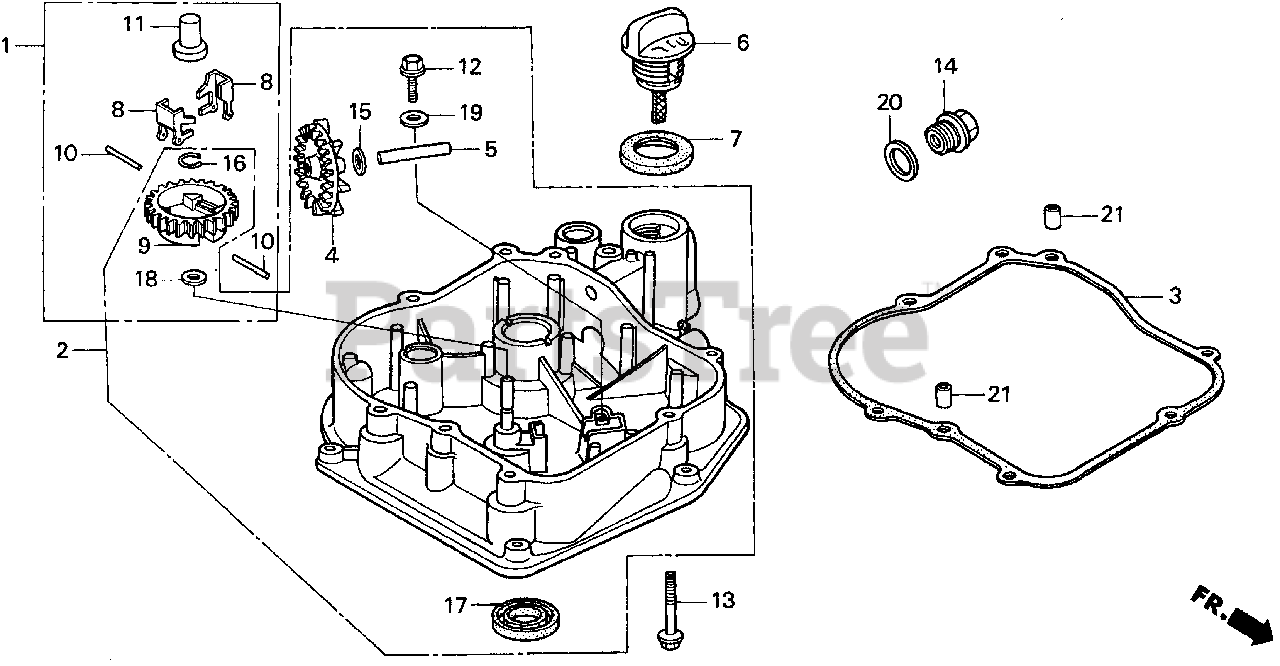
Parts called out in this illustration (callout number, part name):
1	GOVERNOR KIT (STD)
2	PAN ASSY., OIL
3	GASKET, CASE COVER
4	SLINGER, OIL
5	SHAFT, OIL SLINGER
6	CAP, OIL FILLER
7	GASKET, OIL FILLER CAP Use up to Engine SN 1257294.
8	WEIGHT, GOVERNOR
9	HOLDER, GOVERNOR WEIGHT
10	PIN, GOVERNOR WEIGHT
11	SLIDER, GOVERNOR
12	BOLT, FLANGE (5X16)
13	BOLT, FLANGE (6X28) (CT200) Use up to Engine SN 1530314.
14	BOLT, DRAIN PLUG (20MM)
15	WASHER (6MM)
16	CLIP, GOVERNOR HOLDER
17	OIL SEAL (20X34X6)
18	WASHER, PLAIN (6MM)
19	WASHER, PLAIN (5MM)
20	WASHER, DRAIN PLUG (20MM)
21	PIN A, DOWEL (8X14)
